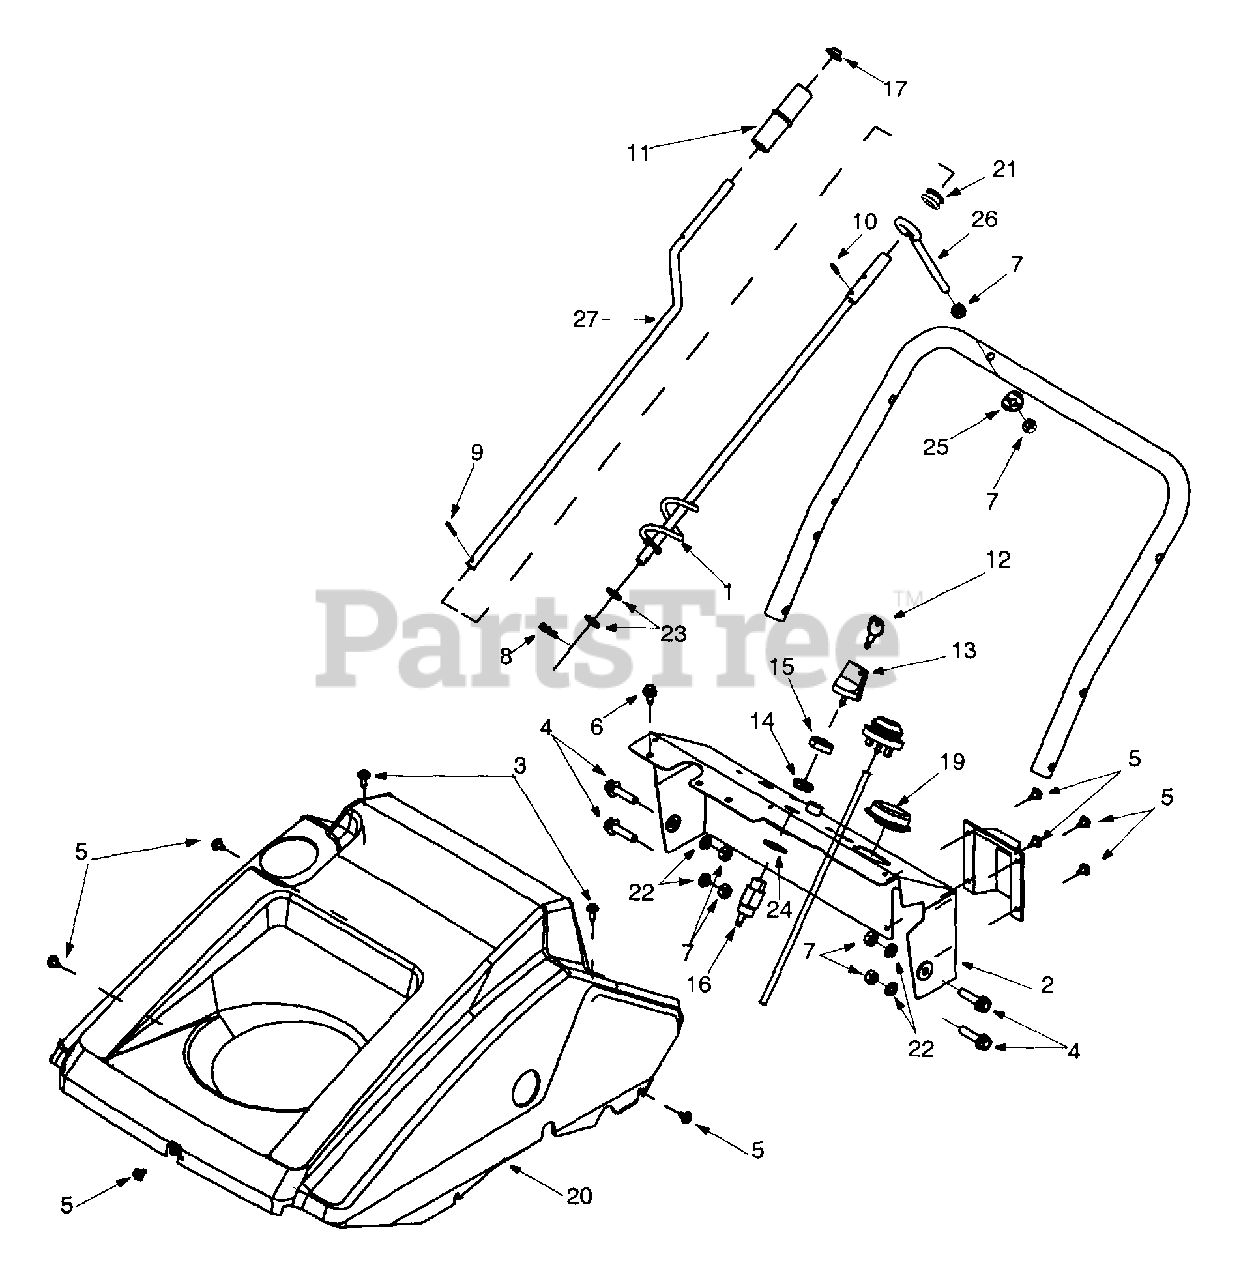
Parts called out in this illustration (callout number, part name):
4	Hex Flange Screw 5/16-18 x 1.25"
5	Special Screw
6	Self-Tapping Screw 1/4-20 x .625"
7	Hex Nut 5/16-18
8	Hairpin Clip
9	Cotter Pin
10	Roll Pin
11	Knob: Chute Crank
12	Ignition Key
14	Ignition Switch Nut
15	Ignition Switch Cap
16	Switch: Recoil Start Key
17	Push Cap
20	Shroud: 21" Black
21	Rubber Grommet
22	Lock Washer: 5/16
23	Flat Washer: .375 x .738 x .063
24	Int. Lock Washer: 5/8 x 1.058 x .046
25	Saddle Washer 320 ID x .93 OD
26	Eyebolt
